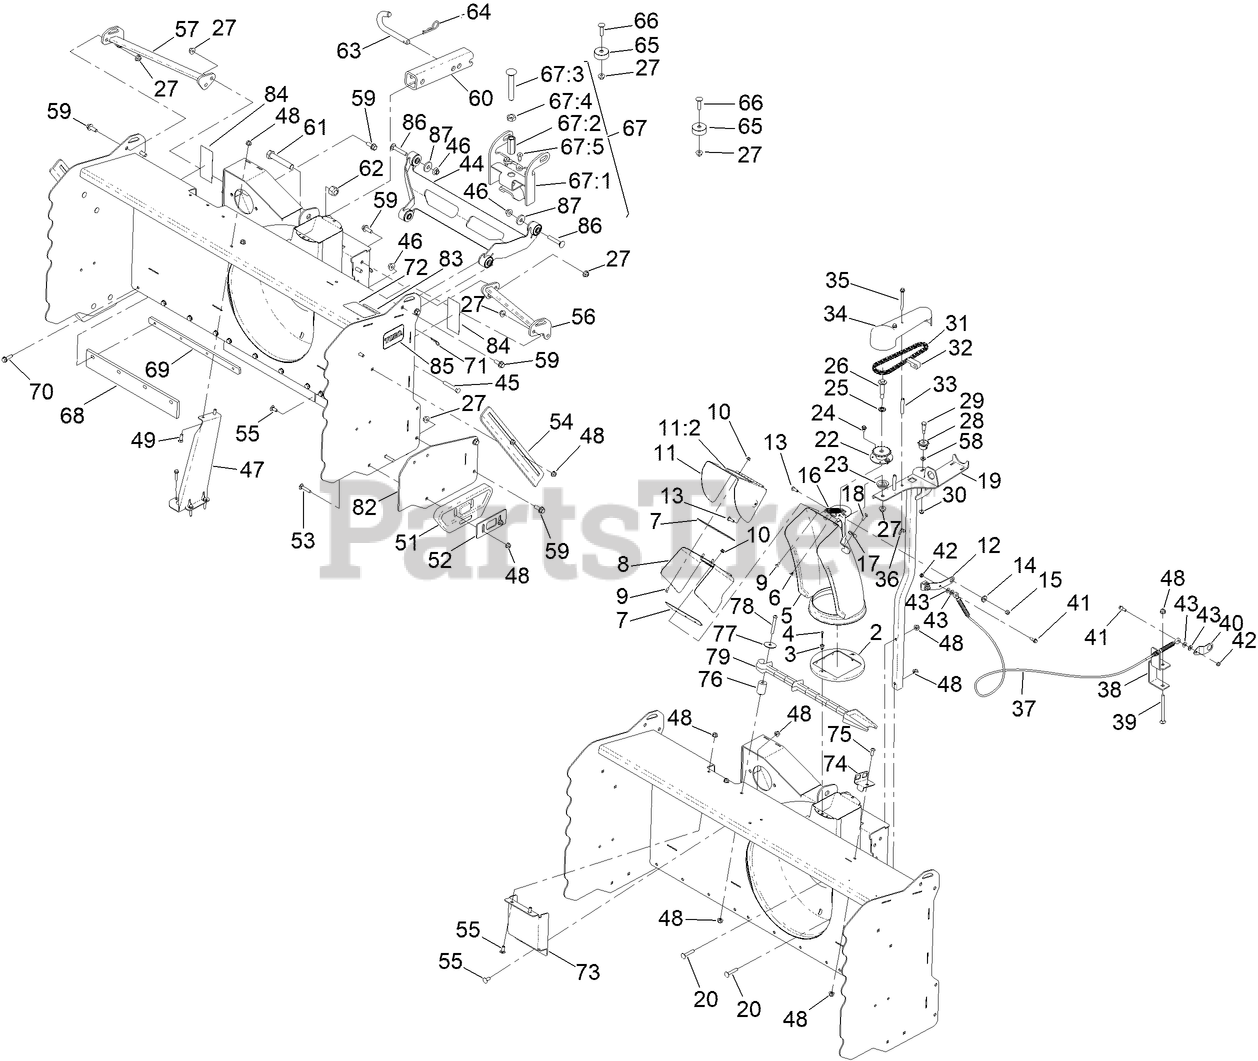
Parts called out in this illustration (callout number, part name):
2	GUIDE-CHUTE
3	GROMMET-SCREW
4	SCREW-PPH
5	LOWER CHUTE ASM
6	PLUG-PLASTIC
7	GASKET-DEFLECTOR
8	MIDDLE DEFLECTOR ASM
9	BOLT-CARR
10	NUT-HF
11	DEFLECTOR ASM
11:2	DECAL-DANGER
12	LINK-DEFLECTOR
13	SCREW-PH
14	BUSHING-PIVOT
15	NUT-HEX
16	SPRING-EXTENSION
17	CLAMP-CABLE
18	SCREW-HWH
19	POST-CHUTE, ASM [BLACK]
20	BOLT-CAR
22	SPROCKET-18 TEETH [BLACK]
23	SPACER-CHUTE
24	SCREW AND WASHER ASM
25	SPACER-BUSHING
26	SCREW-SHOULDER, HWH
27	NUT-HF, NI
28	SPROCKET
29	BOLT-SHOULDER
30	NUT-HF
31	CHAIN DRIVE ASM
32	BLOCK-LINK, CHAIN
33	SPACER
34	COVER - CHAIN
35	SCREW-HHF
36	WINGNUT
37	CABLE-CONTROL, CHUTE
38	BRACKET, CABLE-CHUTE
39	SCREW-CARR
40	BRACKET, CABLE-CHUTE
41	BOLT-SHOULDER
42	NUT-LOCK, NI
43	WASHER-FLAT
44	SNOWTHROWER STRUT ASM
45	SCREW-HH
46	NUT-HF
47	BRACKET-GEARBOX, SUPPORT
48	NUT-HF, NI
49	SCREW-HH
52	PLATE-SKID, MOUNT
53	BOLT-CARR
54	BREAKER-DRIFT, SIDE
55	BOLT-CARR
56	CROSS SUPPORT ASM, LH [RED]
57	CROSS SUPPORT ASM, RH [RED]
58	WASHER-FLAT
59	SCREW-HHF
60	TUBE-HITCH
61	SCREW-HH
62	NUT-LOCK, NI
63	PIN-ATTACH
64	PIN-HAIR
65	BLOCK - STOP
66	SCREW-CARR
67	DOWN STOP KIT
67:1	LOCK BRACKET ASM
67:2	HEX-THREADED
67:3	BOLT-CARRIAGE
67:4	NUT-JAM
67:5	BUMPER-RUBBER
68	SCRAPER-POLY
69	RETAINER-SCRAPER
70	SCREW-HWHTF
71	PIN-HAIR
72	DECAL-DANGER, AUGER
73	PLATE-COVER
74	BRACKET-STICK, CLEANOUT
75	SCREW-HSBH
76	SPACER
77	WASHER-FLAT
78	SCREW-HSBH
79	STICK-CLEANOUT
82	SIDE PLATE - SNOWBLOWER 48
83	DECAL-WARNING
84	TAPE-REFLECTIVE (RED)
85	DECAL
86	SCREW-CARR
87	WASHER
